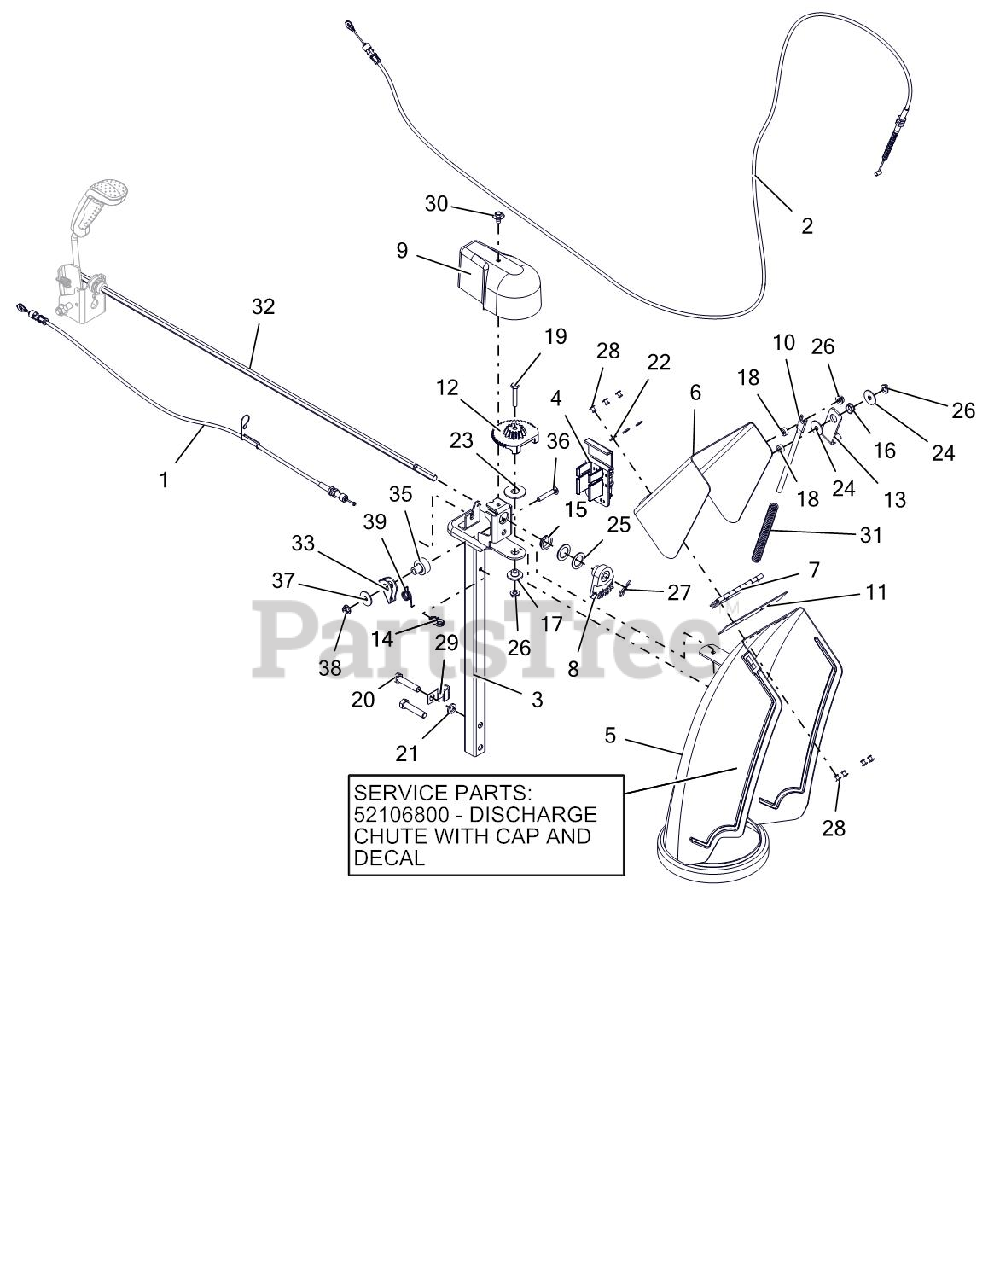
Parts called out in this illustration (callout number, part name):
1	CABLE, CHUTE LOCK, PRO
2	CABLE, DEFLECTOR - DELUXE
3	PEDESTAL, CHUTE - QUICK STICK
4	HOLDER W LARGE SHEAR BOLT /NUT
5	CHUTE,DISCHARGE,NOTCHED,QT
5	KIT, DISCHARGE CHUTE W/DEF QT2
6	CAP, LARGE REMOTE (W/DECAL)
8	GEAR, CHUTE-ACTUATION
9	COVER, CHUTE GEAR
10	ROD, DEFLECTOR CAP
11	CAP SEAL 5.50
12	GEAR, CHUTE
13	BRACKET, CABLE ANCHOR
14	CLIP, CABLE GUIDE
15	BUSHING, POLYLINER-.75 SNAPIN
16	BUSHING, POLYLINER-.50 SNAPIN
17	BSHG-FLG .265X.477X.375X1.00
18	BSHG-SLV .265X.500X.219
19	@BLT-HEX .25-20X1.50 GR5 YWZC
20	@BLT-HEX .38-16X1.75 GR5 YWZC
21	@WSHR-LK .38X.094 REG YWZC
22	WSHR-FL-STL .196X.500X.06 YZ
23	WSHR-FLT-NYL .515X1.375X.093
24	WSHR-FL-STL .281X1.000X.063
25	WSHR-FL-STL.754X1.125X.062YWZC
26	@NUT-LK-CTR-FLG .25-20 YWZC
27	PIN-HAIR INT .08X.18X1.18 YWZC
28	RVT-POP .187 YZ
29	J-CLAMP
30	SCR-TAP .25-20X.50 LGHWH TR YZ
31	SG-COMP .08X.40X6.50 14#/IN
32	ROD, HEX - CHUTE ROTATION
33	ARM, LOCKING
35	BUSHING, LOCK ARM
36	@BLT-RDHDSQNK .25-20X1.50 G5YZ
37	WSHR-FL-STL .281X1.000X.063
38	@NUT-LK-CTR-FLG .25-20 YWZC
39	SG-TORS
